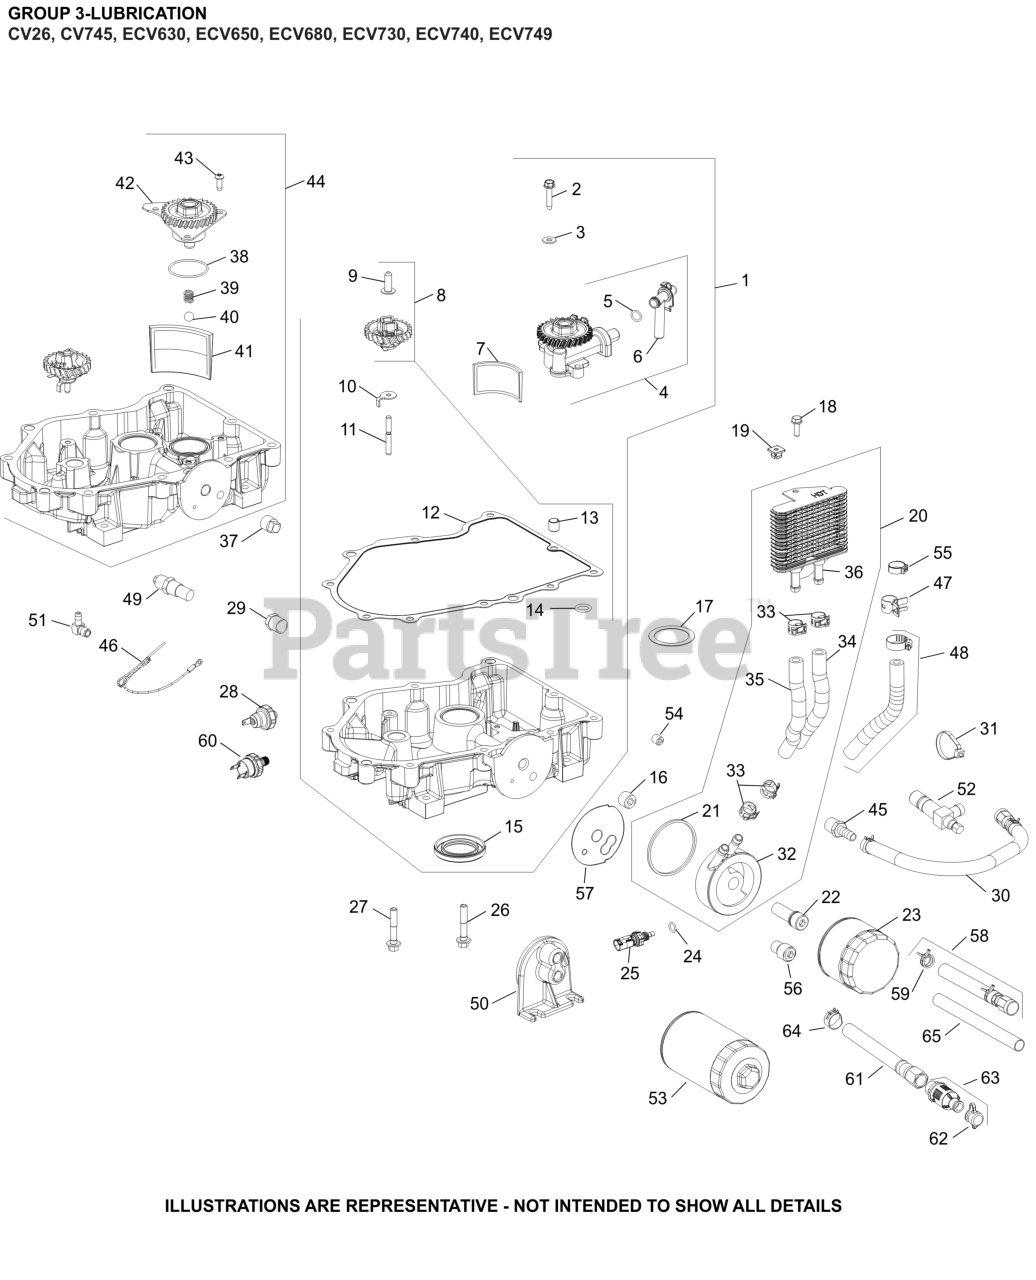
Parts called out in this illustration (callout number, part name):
8	KIT, GOVERNOR GEAR W/PIN
9	PIN, GOVERNOR REGULATING
10	TAB, LOCKING
11	SHAFT, GOVERNOR GEAR
12	KIT, OIL PAN GASKET
19	NUT, PLASTIC - BLACK
21	O-RING, OIL COOLER
23	OIL FILTER
24	O-RING (.5" DIA)
26	SCREW, HEX FLANGE
27	SCREW, FLG M8X1.25X45
33	CLAMP, HOSE LOW PROFILE
37	PLUG, SQ HD PIPE 3/8"
38	O-RING (1.78" DIA)
39	SPRING, COMPRESSION
40	PRESSURE RELIEF BALL
41	SCREEN, OIL
42	PUMP, OIL ASSEMBLY
43	SCREW, BUTTON HEAD
44	PAN, ASSEMBLY OIL (SERVICE)
48	KIT, HOSE 140MM
66	KIT, OIL COOLER
67	KIT, OIL FILTER NIPPLE
68	SCREW, HEX HEAD
69	WASHER, FLAT
